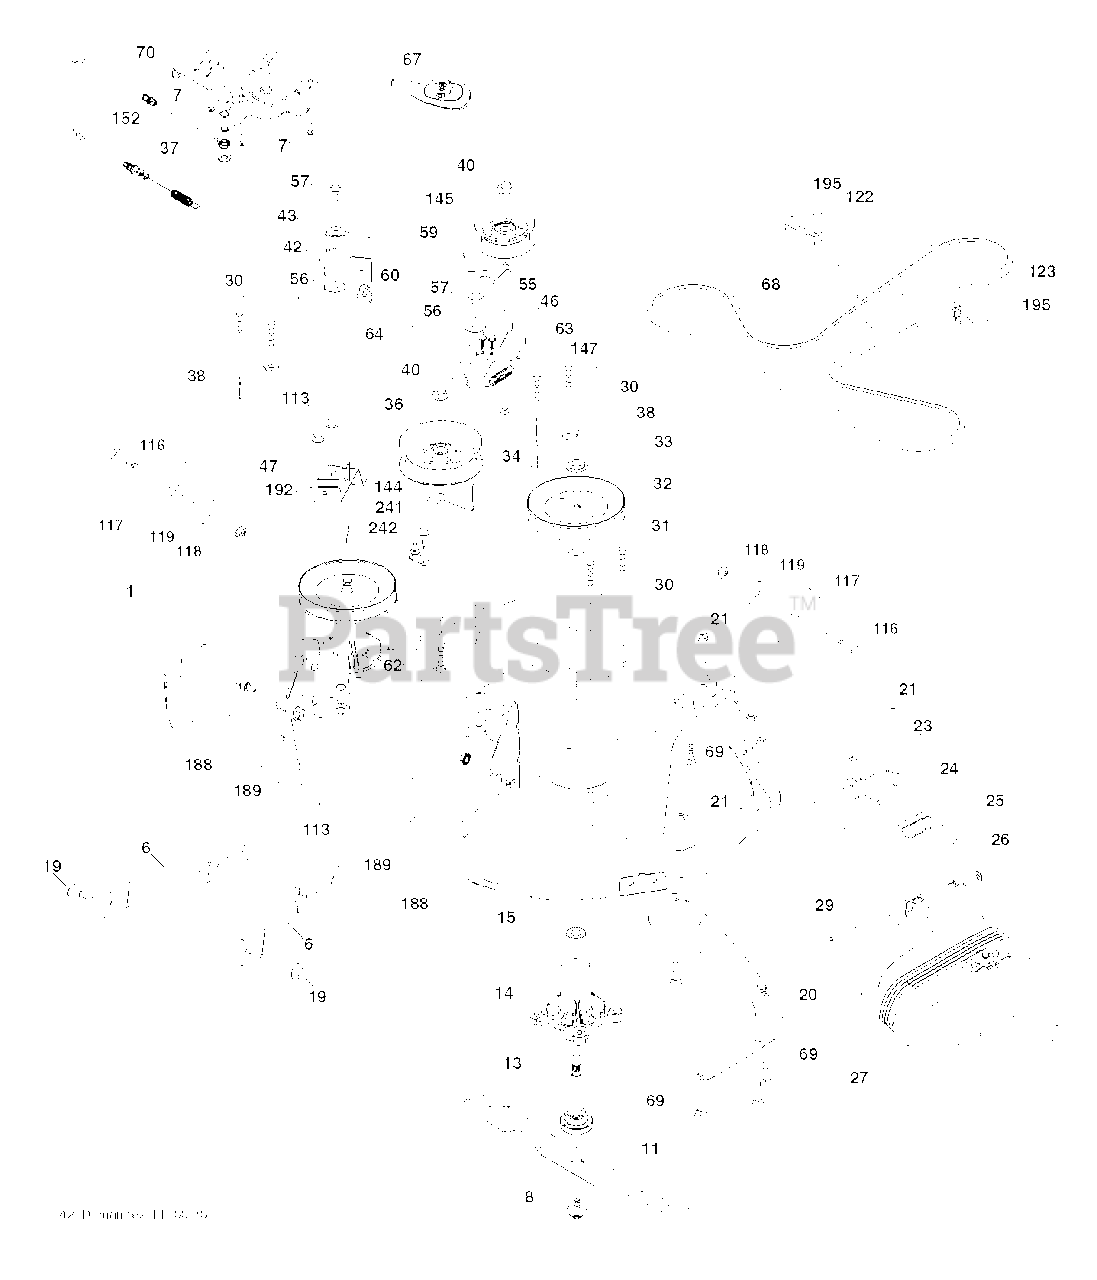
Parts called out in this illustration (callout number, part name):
1	DECK.WELDMENT.42"
6	ARM.SUSPENSION.MOWER.R
7	SCREW.#10 X 0.750.BOS THREAD
8	BOLT.WASHER.ASM.7/16-2
11	42" HI-LIFT BLADE
13	SHAFT.ASM.MDRL.N/GREASE.38
14	HOUSING MANDREL
19	BOLT.SHOULDER
20	BAFFLE.VORTEX
21	LOCKNUT
23	BRKT.DEFLECTOR.38"2005+
24	CAP-SLEEVE LT
25	SPRING.TORSION.DEFLECT
27	SHIELD.DEFLECTOR.MOWER.42"BLAC
29	ROD.HINGE
30	SCREW, WASHER HEAD
31	WASHER.SPACER.MANDREL
32	PULLEY.MANDREL.5.438.PD
33	NUT.FLANGE.LOCK.TOP
34	BOLT.3/8-16X1.50
36	PULLEY.IDLER.2006
38	KEEPER.BELT.MANDREL.PULLEY
40	NUT LOCK FLG 3/8-16 UNC
42	SPRING.TORSION.BRAKE
43	SRPING.TORSION.RETAINE
46	SCREW.1/4-20X5/8
47	BRKT.CLUTCH.CABLE
56	SPACER.RETAINER
57	SCREW 3/8-16X1
60	ARM BRAKE MOWER
62	BOLT
63	ARM BRAKE MOWER
64	LINK BRAKE
68	BELT.DECK.DRIVE.42"
69	BOLT
70	CLUTCH.ASM.MANUAL.LT.PRED
113	BOLT.5/16HEX.WHS.HD
116	Shield Bolt, A 2.41 B 1.66
117	WHEEL.GAGE.HALF.SPOKED
118	NUT LOCK FLG 3/8-16 UNC
119	WASHER
122	KEEPER BELT ENGINE LH
123	KEEPER BELT RH
144	KEEPER.BELT.MOWER
145	PULLEY.IDLER.48"PRIMARY
147	RETURN SPRING
152	CABLE.CLUTCH.MANUAL.
188	STUD.FASTNER.W/ANTI-ROTATE
189	NUT LOCK HEX FLANGE 5/16-18
192	BRKT.BRAKE.STAND.LH.
195	SCREW, 3/8-16X3/4
